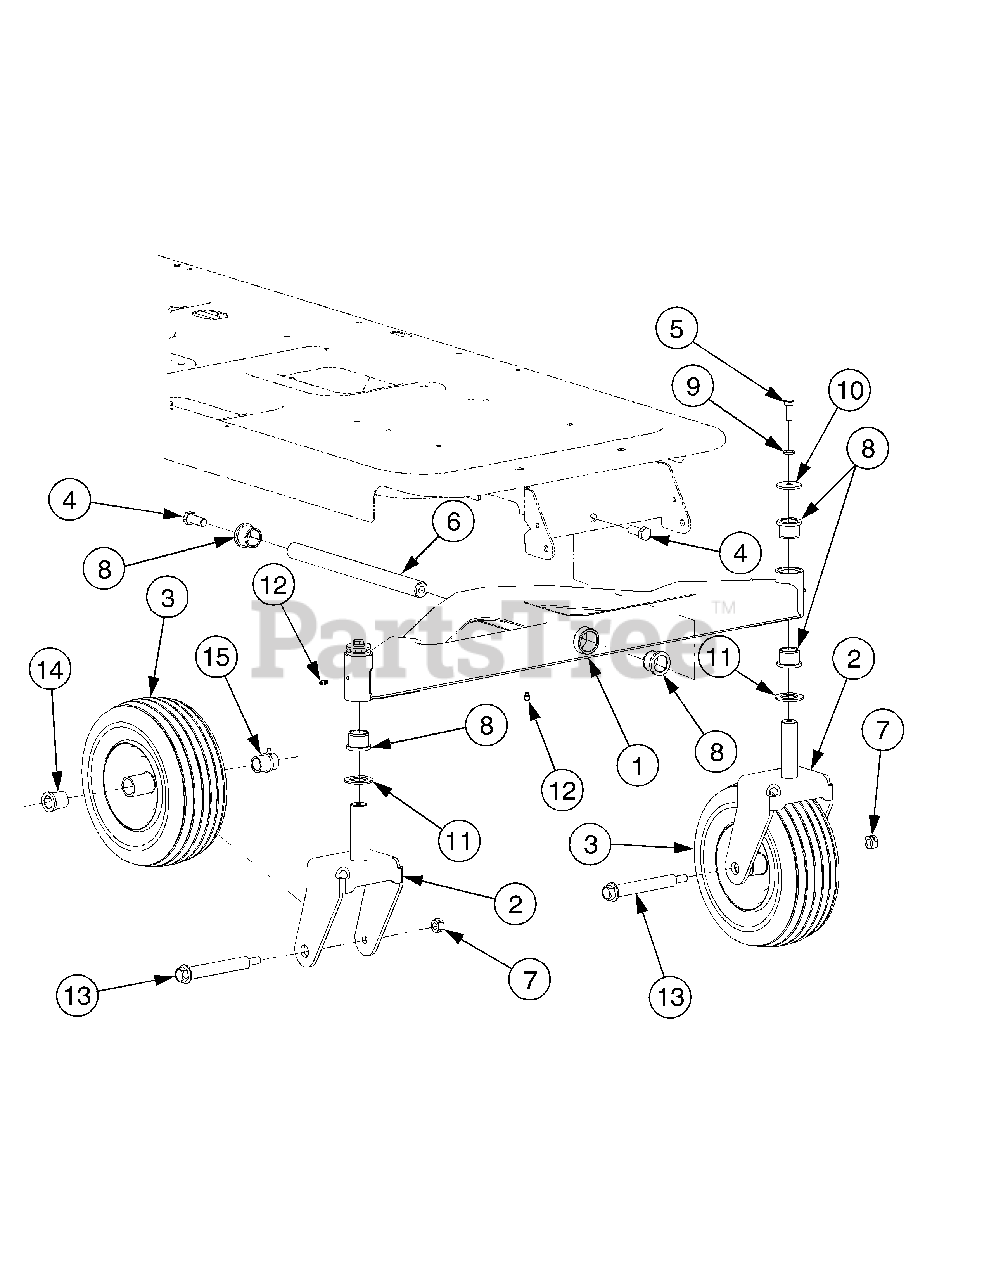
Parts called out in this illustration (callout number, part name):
3	Wheel Assembly, 11.0 x 4.0 x 5.0
4	Screw, Hex Lock, 1/2-13 x 1.25 GR5
5	Screw, Hex Cap, 3/8-16 x 1.0 GR5
6	Shaft, Axle
7	Nut, Hex Lock, 1/2-13 GRB
8	Bearing, Flange, 1.0 x 1.246
9	Washer, Lock, 3/8
10	Washer, Flat, .39 x 1.5 x .134
11	Washer, Flat, 1.0 x 1.75 x .107
12	Fitting, Lube, 3/16 Drive
13	Screw, Shoulder, .75 x 4.75:7/16-14
14	Bearing, Flange, .76 x 1.0 x 1.2
15	Bearing, Flange, .76 ID w/Lube Ftg.
